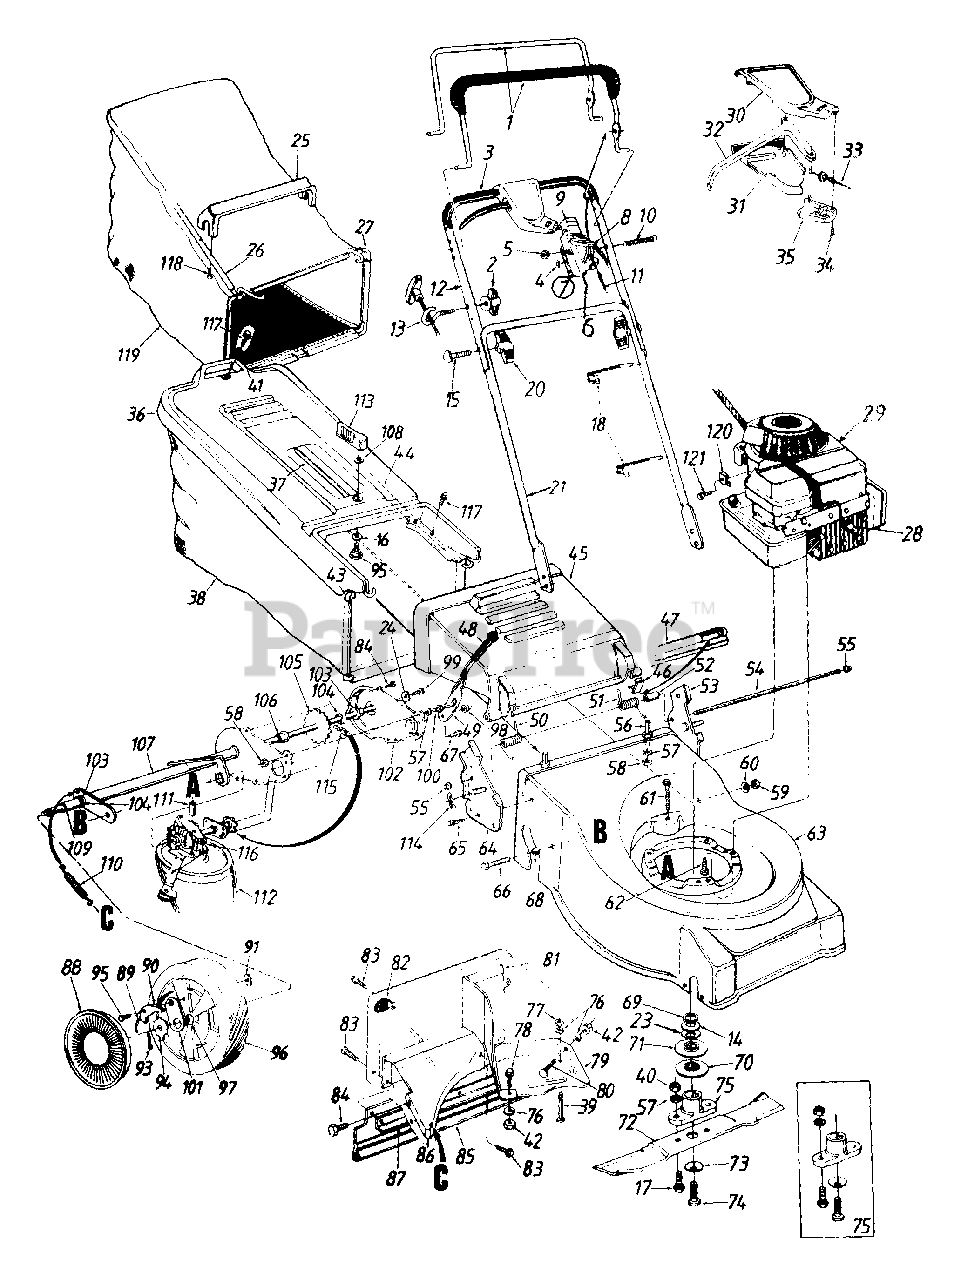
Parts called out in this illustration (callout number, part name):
1	Control Handle
2	Wing Nut 1/4-20 Thd.
3	Foam Grip
4	Spr. Wash..66" I.D.
5	Hex L-Nut 1/4-20 Thd.
6	Throttle Cable - 55" (B&S)
6	Throttle Cable - 51" (Tecumseh)
7	Throttle Box Comp.
8	Throttle Lever
9	Throttle Body
10	Oval C-Sunk Scr.
11	Control Cable - 40.5" (B&S)
11	Control Cable - 51" (Tecumseh)
12	Upper Handle
13	Rope Guide
14	Spr. Wash..89" I.D.
14	Bell-Wash. 1.01" I.D.
14	Wave Wash. 1" I.D. (Tec. Engine)
15	Curved Hd. Bolt 5/16-18 x 2"
16	Bowed Washer
17	Hex Bolt 3/8-24 x 1" Lg.
18	Cable Tie
20	Hand Knob
23	Fl-Wash..88" I.D. x 1.85"
24	Bell-Wash..265" I.D. x .75"
25	Bag Handle
26	Rear Catcher Frame
27	Front Catcher Frame
28	Spark Plug Boot
29	Engine
30	Control Cover Half - Upper
31	Control Cover Half - Lower
32	Control Lever
33	Drive Cable - 51" Lg.
34	Flat C-Sunk Hd. Tap Scr. #10 x .75" Lg.
35	Cable Mtg. Cap
36	Hardtop Bag Covering
37	Hardtop Handle
38	Grass Bags
39	Truss Mach. Scr. 1/4-20 x 1.0" Lg.
40	Hex Nut 3/8-24 Thd.
41	Fl-Wash..281" I.D. x .62"
42	Hex Nut 1/4-20 Thd.
43	Front Catcher Frame
44	Rear Catcher Frame
45	Chute Deflector
46	Deflector Plug
47	Seal - Extrusion
49	Spring Lever
50	Torsion Spring - R.H.
51	Torsion Spring - L.H.
52	Spacer .255" I.D.
55	Cap Speed Nut
56	Shld. Pin 3/8-24 x 1.43" Lg.
57	L-Wash. 3/8" I.D.
58	Hex Jam Nut 3/8-24 Thd.
59	Hex L-Nut 3/8-24 Thd.
60	Bell-Wash..38" I.D. x.88"
61	Hex Wash. Hd. Tap Scr. 1 4-20 x 1.5" Lg.
62	Hex L-Wash. Hd. Scr. 3/8-16 x 1" Lg.
63	21" Deck Ass'y.
64	Handle Brkt. Ass'y.- R.H.
65	Hex L-Wash. Hd. AH-Tap Scr. 1/4 x .62" Lg.
66	Hex Wash. Hd. Tap Scr. 3/8-16 x .75" Lg.
67	Hex Wash. Hd. Tap Scr. 1/4-20 x .5" Lg.
68	Spacer .383" I.D.
69	Crankshaft Spacer
69	Serr.-Wash. 1" I.D.
70	Pulley Half - Lower
71	Pulley Half - Upper
71	Pulley Half
72	21" Blade
73	Bell-Wash..39" I.D.
73	Bell-Wash..46" I.D.
74	Hex Bolt 3/8-24 x 1.5" Lg.
74	Hex Bolt 7/16-20 x 1.5" Lg.
75	Blade Adapter Kit
76	L-Wash. 1/4" I.D.
77	Hex Jam Nut 1/4-20 Thd.
78	Hex Bolt 1/4-20 x .85" Lg.
79	Rear Belt Baffle
80	Carr. Bolt 1/4-20 x .50" Lg.
83	Torx Mach. AB-Tap Scr. 1/4 x .62" Lg.
84	Hex B-Tap Scr. 1/4 x .38" Lg.
85	Rear Flap
86	Rear Chute Baffle
89	Plastic Spring
90	Pawl .345" I.D.
91	Weld Top L-Nut 1/4-20 Thd.
93	Cotter Pin 1/8" Dia.
94	Ratchet Wheel 1.62" O.D.
95	Shld. Bolt .342" Dia. x .268"
96	Wheel Ass'y. Comp.- Rear
97	Bearing 1/2" I.D.
98	Shld. Spacer .50" Dia.
99	Hex Bolt 1/4-20 x .62" Lg. (Gr. 5)
100	Shld. Pin 3/8-24 x 1.43" Lg.
101	Pawl Plate
104	Fl-Wash..531" I.D. x .93"
105	Rear Axle Ass'y.
106	Hex Flange Bearing
109	Spacer .513" I.D.
110	Extension Spring 3.8" Lg.
111	Spacer .325" I.D.
112	V-Belt
113	Grass Catcher Locking Knob
114	Internal Cotter Pin 8/16" Dia.
115	#48 Chain .50" Pitch x 30 Links
116	Transmission Comp. (See Breakdown)
117	Hex L-Wash. H.D. AB-Tap Scr. 1 4 x .62" Lg.$$
118	Hex AB-Tap Scr. #12 x 1.25" Lg t
119	Grass Bags
120	Cable Clamp (B&S)
121	Hex Self-Tap Scr. #10-32 x .62" Lg. (B&S)
